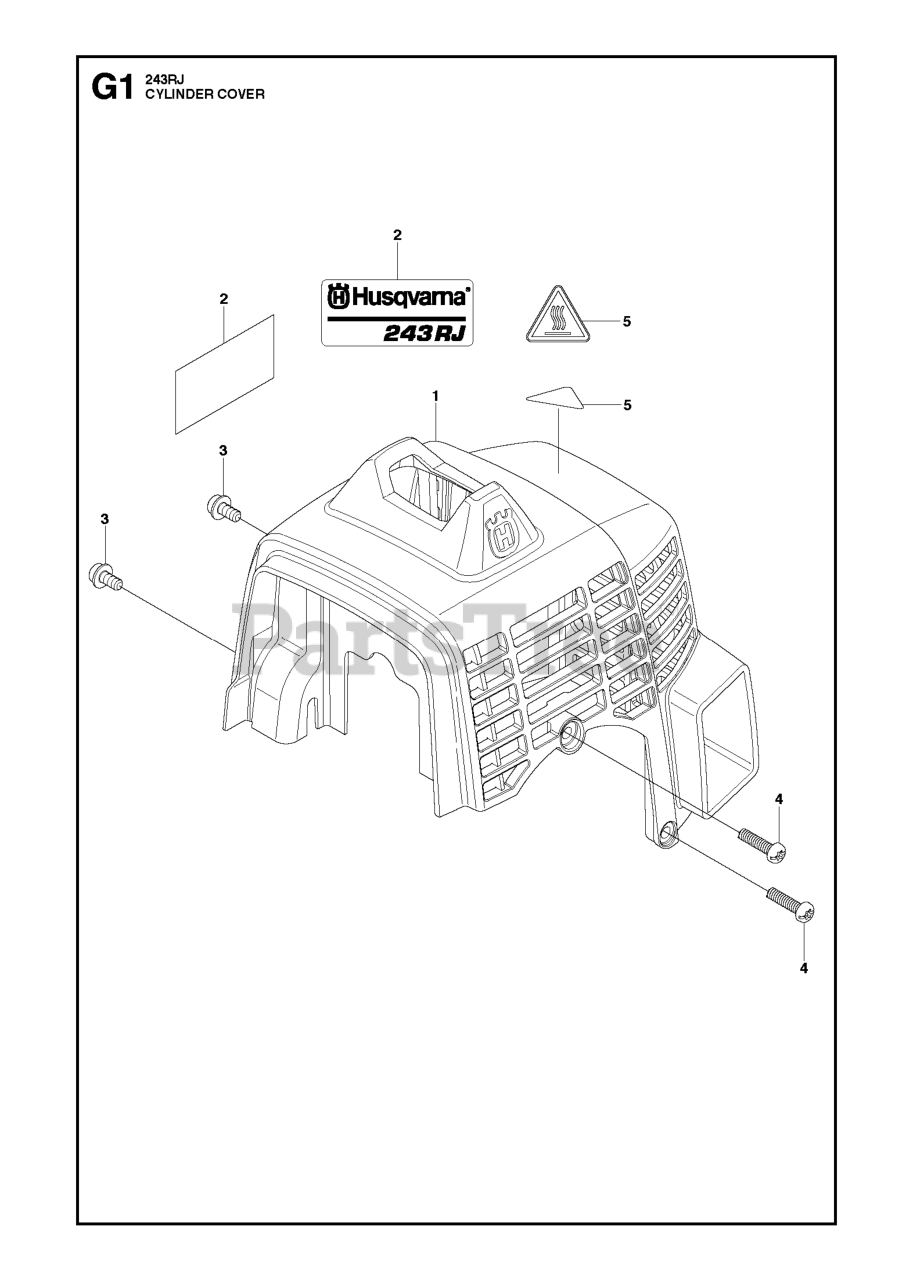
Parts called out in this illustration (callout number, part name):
1	COVER ENGINE
3	BOLT (RPLS T495051010-11)
4	SCREW, TORX (RPLS T4970-52001)
5	LABEL HOT CAUTION
